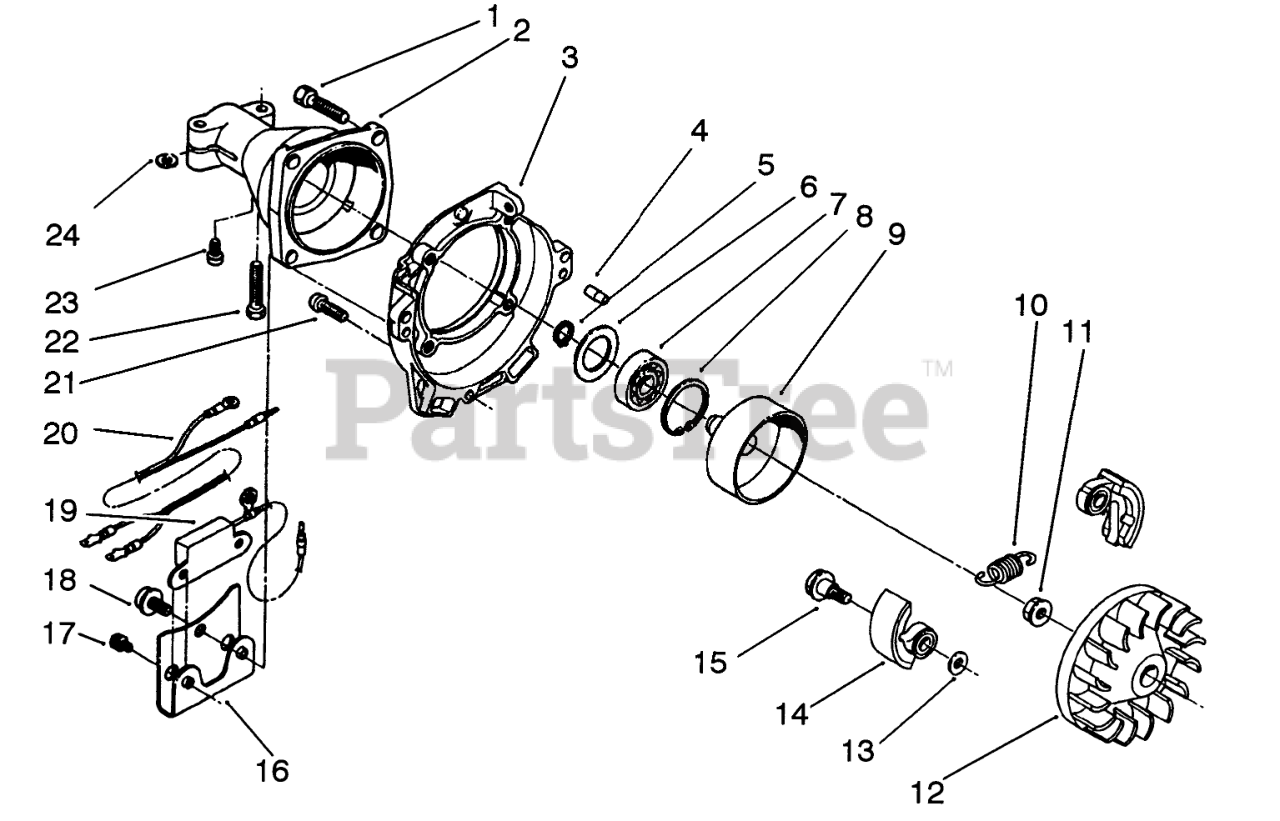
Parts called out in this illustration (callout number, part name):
1	Bolt/Washer
2	CLUTCH CASE
3	FAN CASE
5	SNAP RING
6	Washer
7	BALL BEARING
8	SNAP RING
9	CLUTCH DRUM
10	SPRING
13	WASHER
14	SHOE, CLUTCH
15	CLUTCH BOLT
16	Bracket-Unit
17	SCREW W/ WASHER
18	SCREW & WASHER
19	TRANSISTOR
20	WIRE,LEAD
21	BOLT & WASHER
22	BOLT-WASHER/ENG
23	Screw/Washer
24	WASHER
